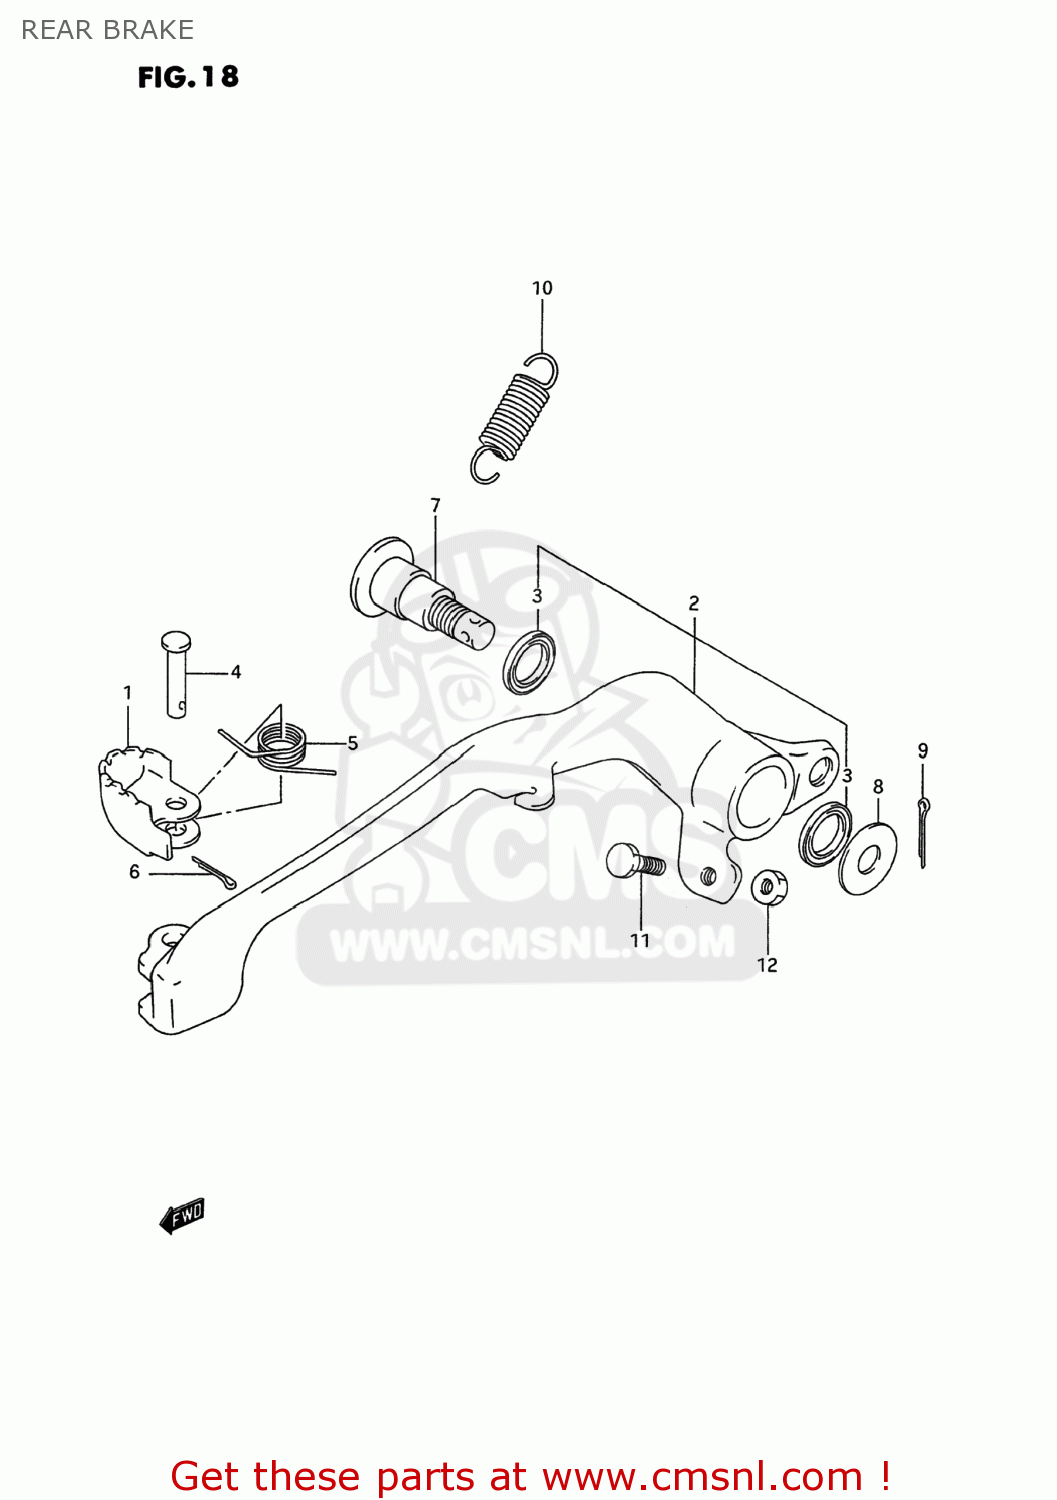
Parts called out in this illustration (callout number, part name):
1	PEDAL,BRAKE
2	ARM,BRAKE PEDAL
3	SEAL,OIL(15X21X3)
4	PIN(6X23.5)
5	SPRING
6	PIN
7	SHAFT,BRAKE PEDAL
8	WASHER
9	PIN 20X20
10	SPRING
11	BOLT(6X23)
12	NUT
